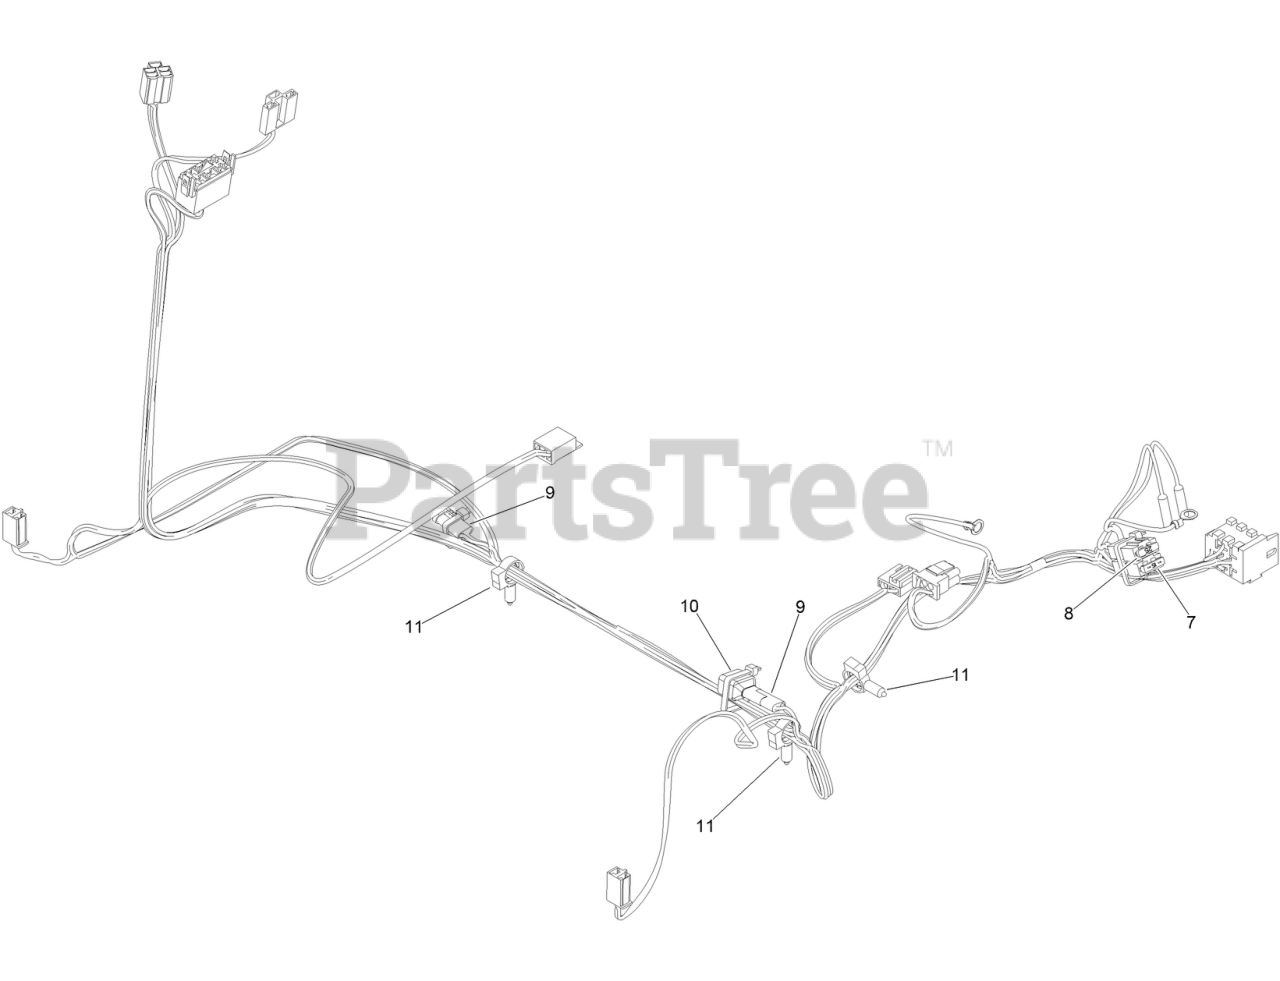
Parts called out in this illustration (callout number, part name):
7	FUSE-BLADE, 15 AMP
8	FUSE-BLADE, 25 AMP
9	CONNECTOR-MOLDED, 1F,1M
11	CLIP-TUBING, HARNESS
